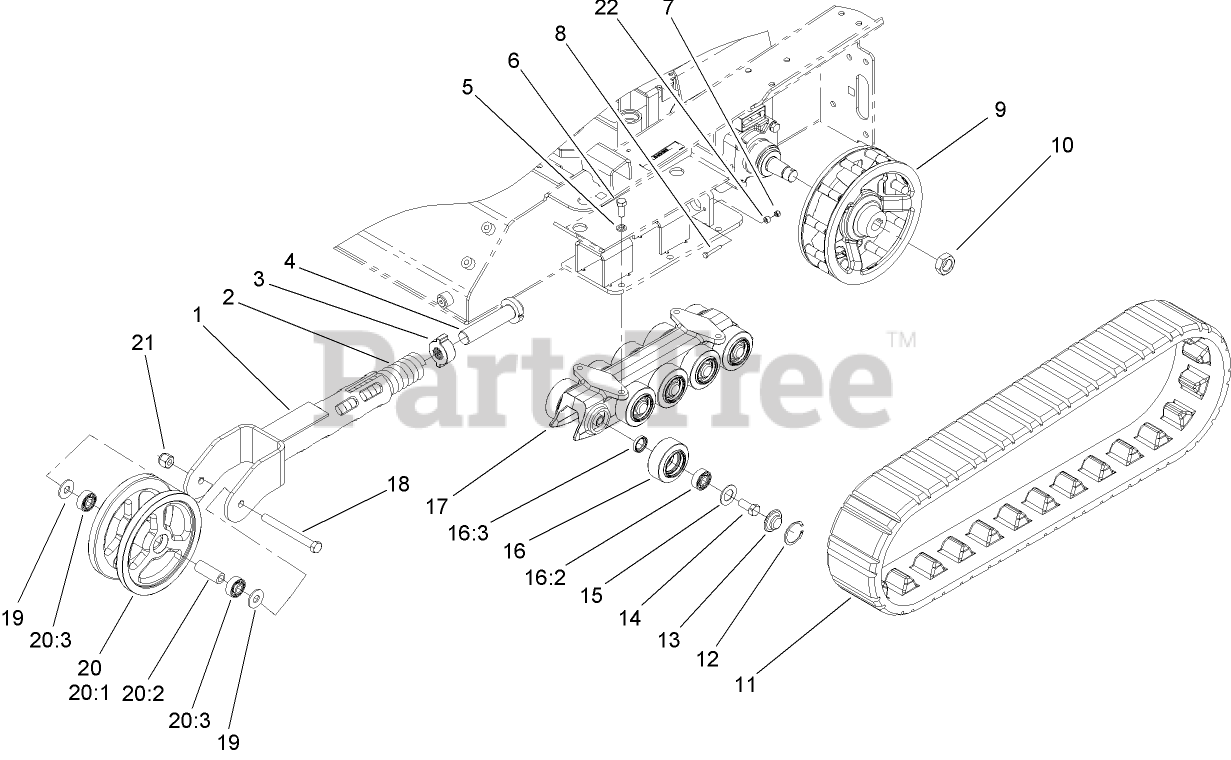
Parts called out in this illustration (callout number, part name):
1	ARM-TENSIONER
2	SPRING-COMPRESSION
3	BLOCK-TENSIONER
4	BOLT-TENSIONER
5	WASHER-LOCK
6	SCREW-HH
7	NUT-HHF
8	SCREW-HH
9	WHEEL-DRIVE
10	NUT-HEX
11	TRACK
12	RING-SNAP, INTERNAL
13	CAP-WHEEL, BEARING
14	SCREW-HH
15	Gasket-Bogie
16	Road Wheel ASM
16:2	BEARING
16:3	SEAL-OIL
17	GUIDE-TRACK
18	SCREW-HH
19	WASHER-FLAT
20	TENSIONER WHEEL ASM
20:1	WHEEL-TENSIONER
20:2	SPACER-WHEEL, TENSIONER
20:3	BEARING
21	NUT-HEX
22	SPACER
